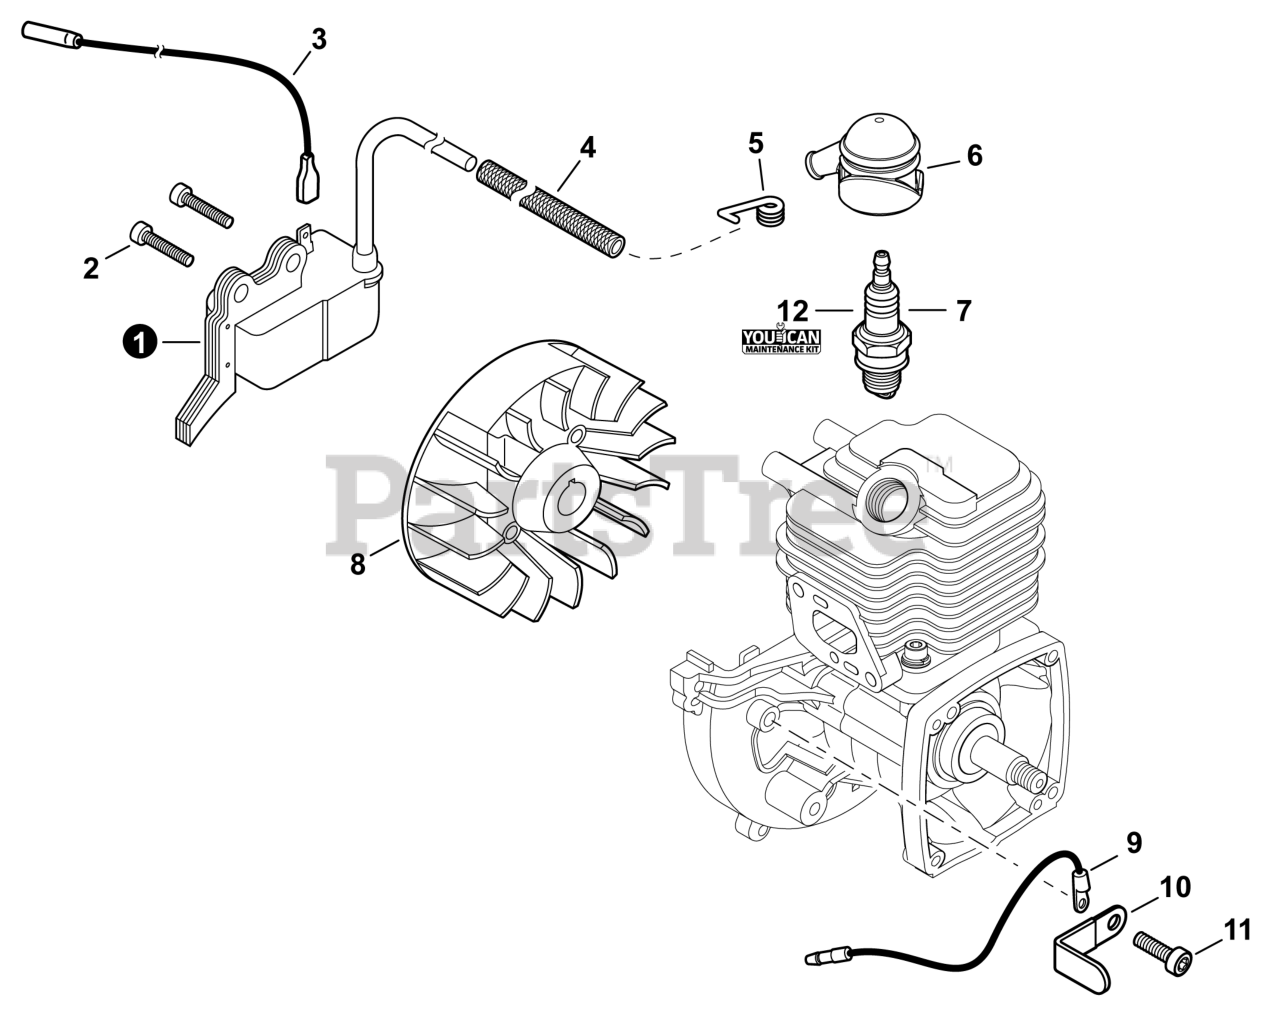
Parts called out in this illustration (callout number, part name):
1	COIL, IGNITION
2	BOLT, TORX 4x20
3	LEAD - IGNITION L= 210
4	TUBE, INSULATOR
5	TERMINAL, SPARK PLUG
6	CAP, SPARK PLUG
7	SPARK PLUG - BPMR8Y
8	FLYWHEEL
9	LEAD - GROUND L= 115
11	BOLT, TORX 5x10
12	TUNE-UP KIT - YOUCAN™
